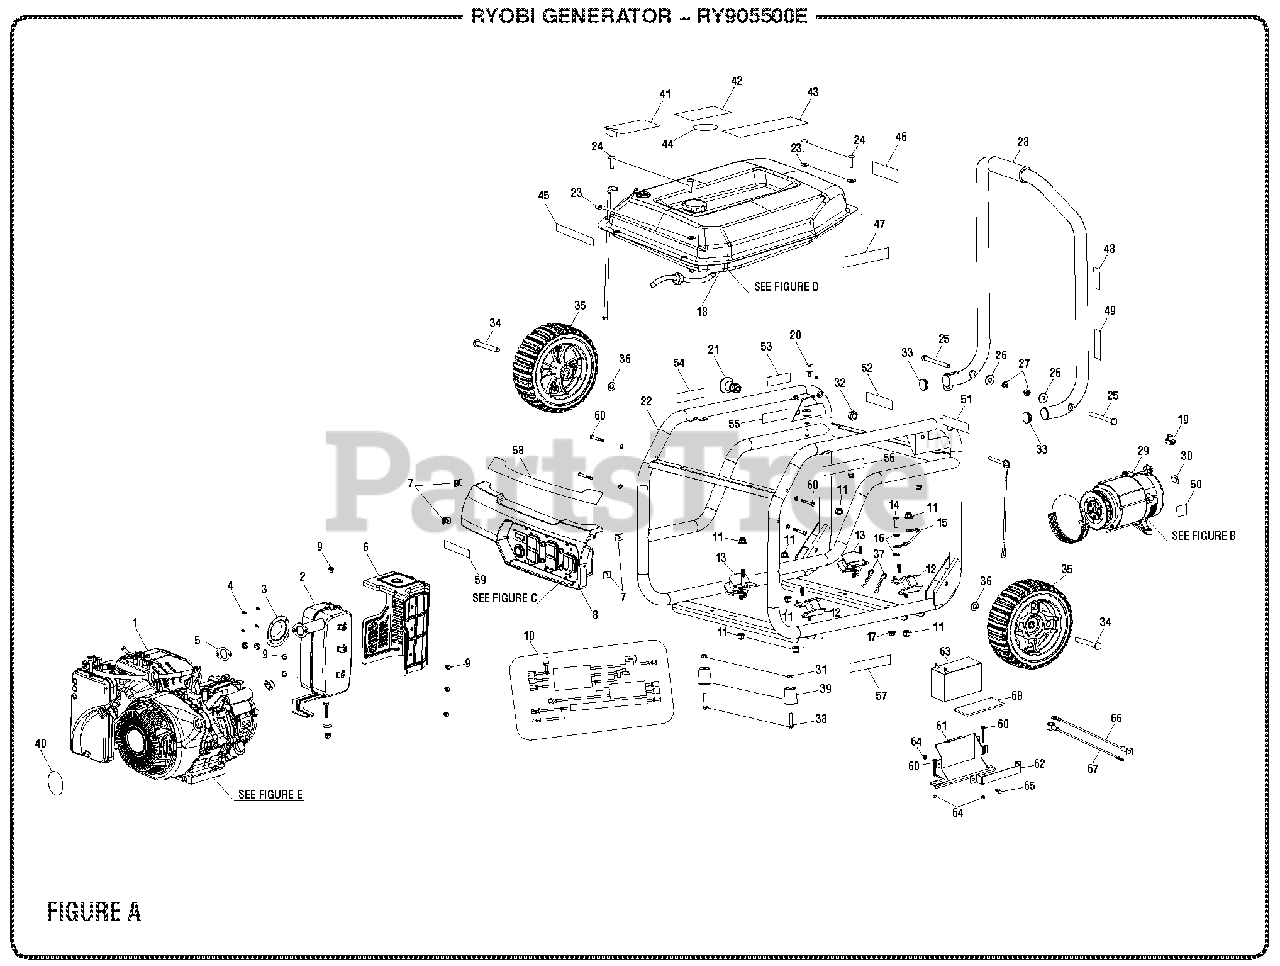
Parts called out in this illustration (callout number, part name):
3	Spark Arrester
4	Screw (8-32 x 3/8 in.)
5	Exhaust Gasket
6	Heat Shield
7	U-Clip (M6)
8	Control Panel Assembly
9	Bolt (M6 x 9 mm, Hex Flange Hd.)
10	Wire Assembly
11	Lock Nut (M8)
12	Isolator (Large)
13	Isolator (Small)
14	Bolt (5/16-18 X 0.75 in.)
15	Ground Wire Assembly
16	Star Washer (5/16 in.)
17	Flange Nut (5/16-18)
18	Fuel System
19	Rubber Boot
20	Handle Bumper
21	Quick Release Pin
22	Carrier Assembly
23	Washer (1/4 in., Type A)
24	Screw (1/4-20 x 1 in., T30 Torx Hd.)
25	Handle Pivot Bolt
26	Washer (5/16 in.)
27	Lock Nut (5/16-18)
28	Handle Assembly
29	Generator Head Assembly
30	Ground Lug
31	Lock Nut (M8)
32	Lock Nut (1/2-20)
34	Axle Bolt
36	Washer (M10)
37	Hitch Pin
38	Bolt (M8 x 45 mm, Hex Flange Hd.)
40	Recoil Label
41	Notice Hangtag
42	Warning Label
43	CPSC Label
44	Fuel Stabilizer Label
45	Logo Label
46	Combustion Warning Label
47	Start Label
48	Fuel Stabilizer Label (SP/FR)
49	E85 Label
50	Ground Label
51	Ground Warning Label
52	Fire Danger Label
53	Pin Release Label
54	Inquiries Label
56	Fire Distance Label
57	Lubricant Label
58	Performance Label
59	Choke Label
60	Screw (M6 x 50 mm, T30 Torx Hd. )
61	Battery Tray
62	Battery Bracket
63	Battery
64	Lock Nut (M6)
65	Bolt (M6 x 16 mm, Hex Hd.)
66	Battery Cable (Red)
67	Battery Cable (Black)
68	Battery Tray Gasket
